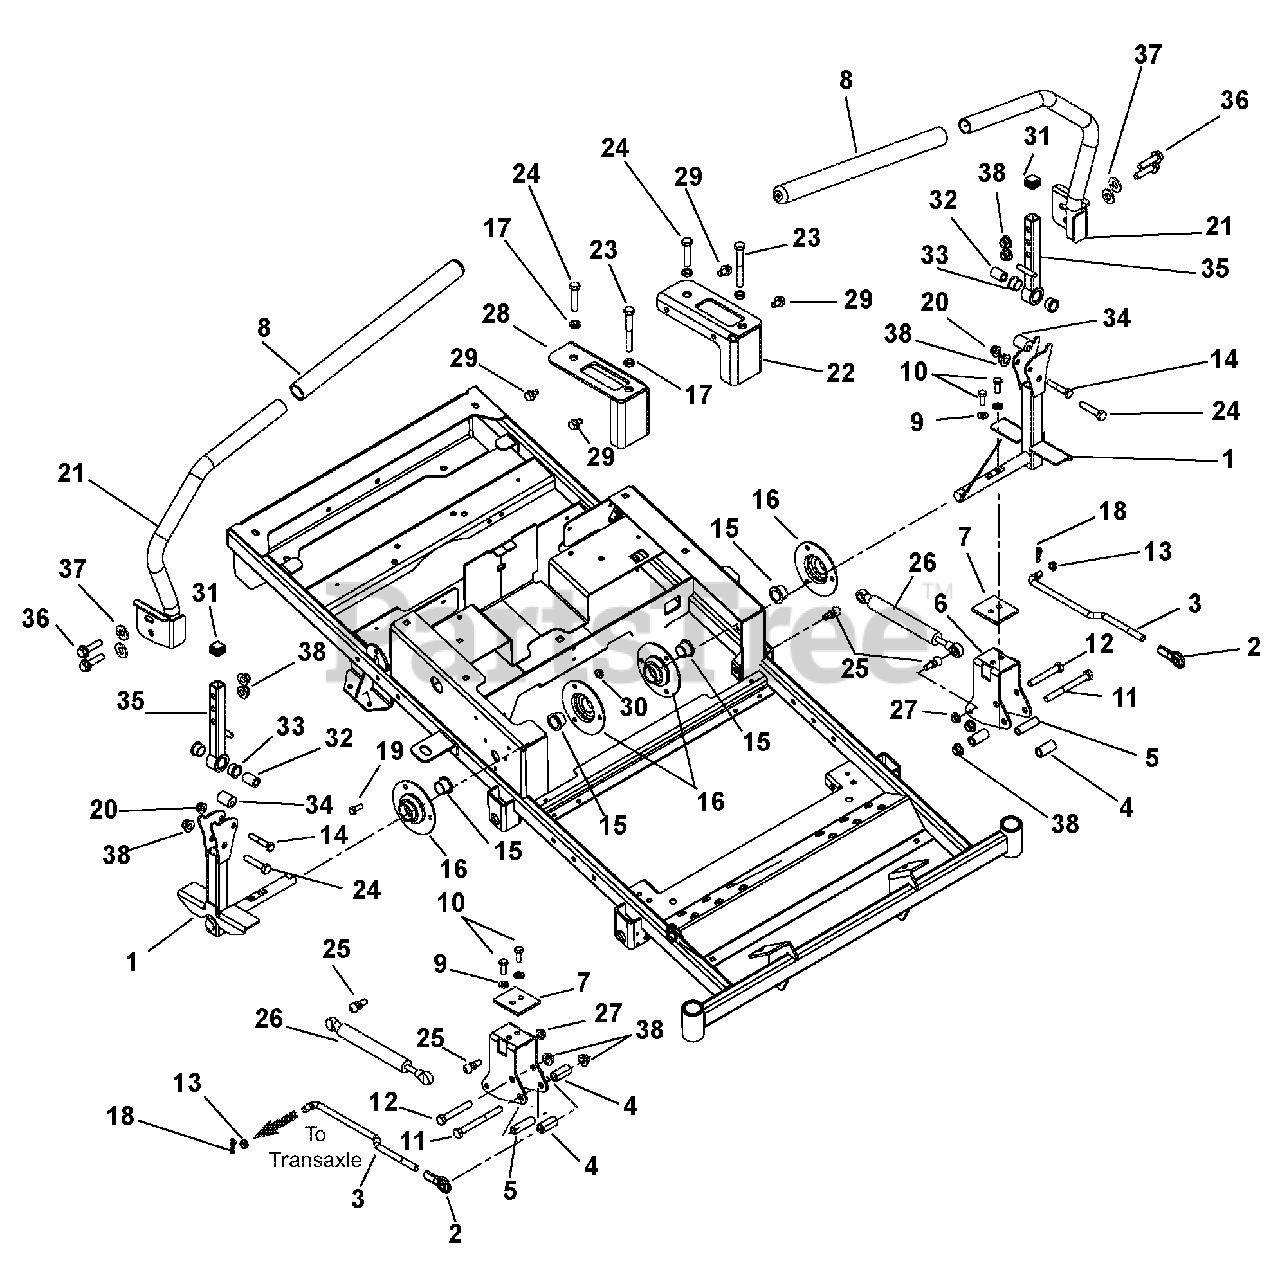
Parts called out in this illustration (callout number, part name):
1	Weldment, Control Arm
2	Rod End, .38 Right Hand
3	Link, Transmission
4	Bushing, Spacer .390 x .625 x 1.25 Promaster
5	Spacer, Steering
6	Bracket, Steering
7	Plate, Steering Reinforcing
8	Grip, Handlebar 15" Foam
9	Washer, Locking .31 x .078
10	Bolt, Hex .31-18 x 1.00 Grade 8
11	Bolt, Hex .38-16 x 3.75 Grade 5
12	Bolt, Hex .38-16 x 2.50 Grade 5
13	Bushing, Polyliner 322-C
14	Bolt, Hex .31-18 x 1.75 Grade 5
15	Bushing, Flange .750 x 1.000 x .625 x 1.250
16	Bearing Flange
17	Nut, Hex Jam .375-16
18	Pin, Hair Internal .08 x .18 x 1.18
19	Bolt, Hex .25-20 x .75 Grade 5
20	Nut, .31-18 Nyloc Flange
21	Weldment, Steering Handle Right Hand
22	Bracket, Left Hand Speed Control
23	Bolt, Hex .38-16 x 3.00 Grade 5
24	Bolt, Hex .375-16 x 1.750 Full Thread
25	Stud, Ball
26	Damper, Control
27	Nut, Locking Top Flange .31-18
28	Bracket, Right Hand Speed Control
29	Screw, Tapping .31-18 x .50 Hex Washer Head
30	Nut, Locking Top Flange .25-20
31	Cap Plug, Square .75-14-20 Ribbed
32	Spacer, .375 x .625 x .970 (PM)
33	Bushing, Flange, .625 x .750 x .450 x .875
34	Bushing, Eccentric .31 x .75 x .97
35	Weldment, Upper Control Arm
36	Bolt, Serrated Hex Flange Washer Head .375-16 x 1.25
37	Washer, Flat Steel .406 x .812 x .065
38	Nut, Locking Center Jam .375-16
